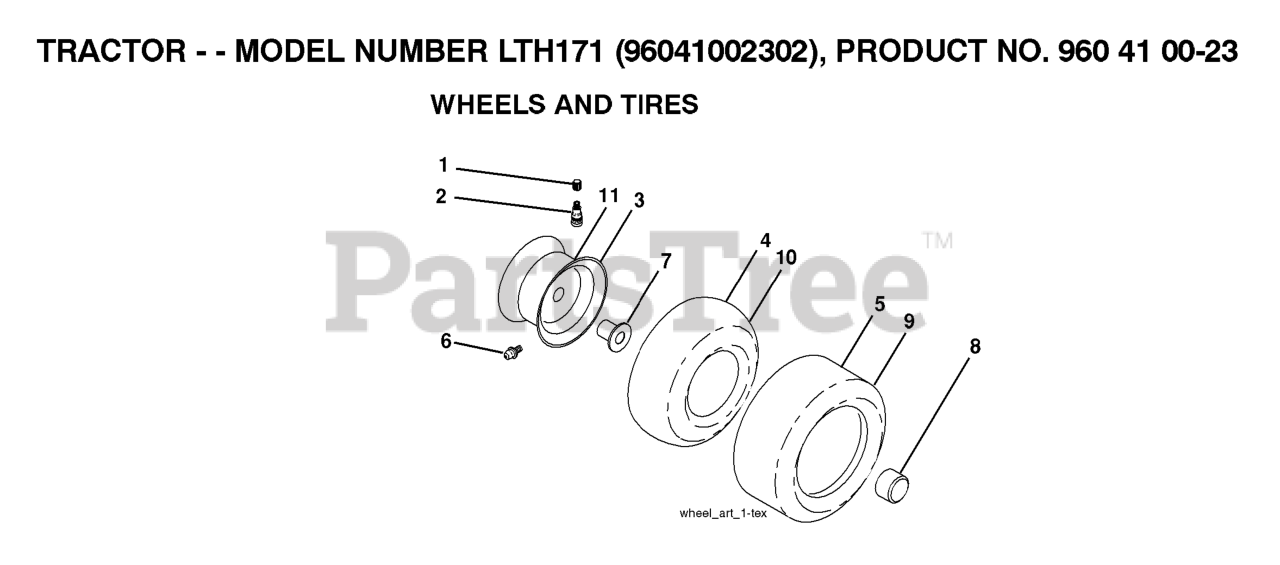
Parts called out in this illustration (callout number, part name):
2	VALVE STEM LT
3	RIM ASM 6" FRONT SILVER
4	TUBE.5.3/4.5/6
5	TIRE HEAVY DUTY
6	FITTING LT
7	BEARING T
8	CAP, AXLE BLK
9	TIRE.TS.20X10-8
10	TUBE
11	RIM ASM 8" REAR SILVER
